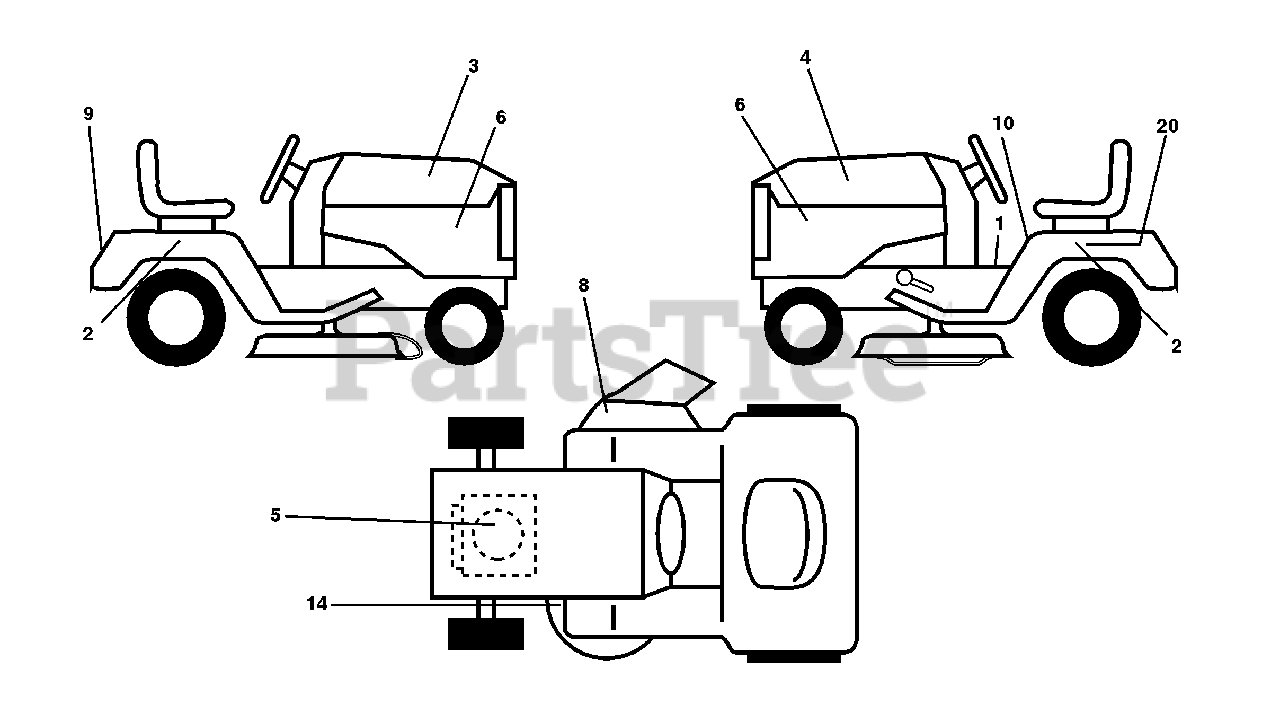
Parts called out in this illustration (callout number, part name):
1	Decal Oper. Step Thru Eng/Fr
2	Decal Fender Auto Husq Radius
3	Decal Hood RH
4	Decal Hood LH
5	Decal HP Engine
6	Decal Pnl Side
8	Decal Warning
9	Decal Fender Husq
10	Decal Fender Danger Eng/Fr
14	Decal V-Belt Schematic
20	Decal Bat Dan/Psn
MK380	Mulcher Kit with Blades
